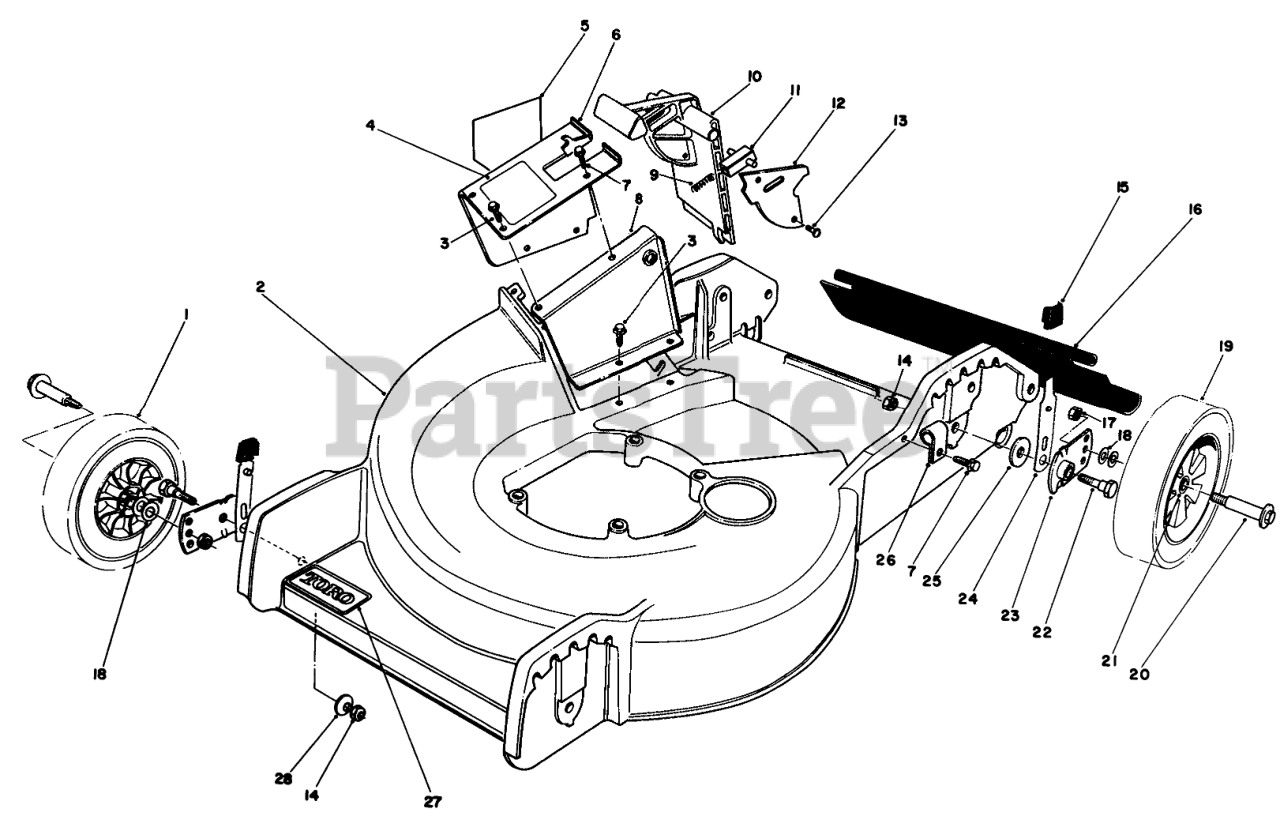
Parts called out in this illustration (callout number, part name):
1	Wheel & Tire Assembly (Incl. Ref. #21)
2	Housing
3	SCREW
4	DECAL - CAUTION
5	DECAL-DANGER
6	Tunnel-Outer (Incl. Ref. #4 & 5)
7	SCREW
8	Tunnel-Inner
9	SPRING-COMPRESSION, LATCH
10	Door-Mulching
11	Door Latch
12	DOOR COVER
14	NUT-LOCK, NI
15	KNOB-ARM
16	SHIELD - TRAILING
17	Nut
18	WASHER
19	Wheel & Tire Assembly (Incl. Ref. #21)
20	BOLT-WHEEL
21	BUSHING
22	5/16-18 PIVOT SCREW
23	PIVOT ARM ASSY
24	SPRING ARM ASM
25	PIVOT WASHER
26	CLAMP-NYLON
27	DECAL
28	WASHER-BELLEVILLE
